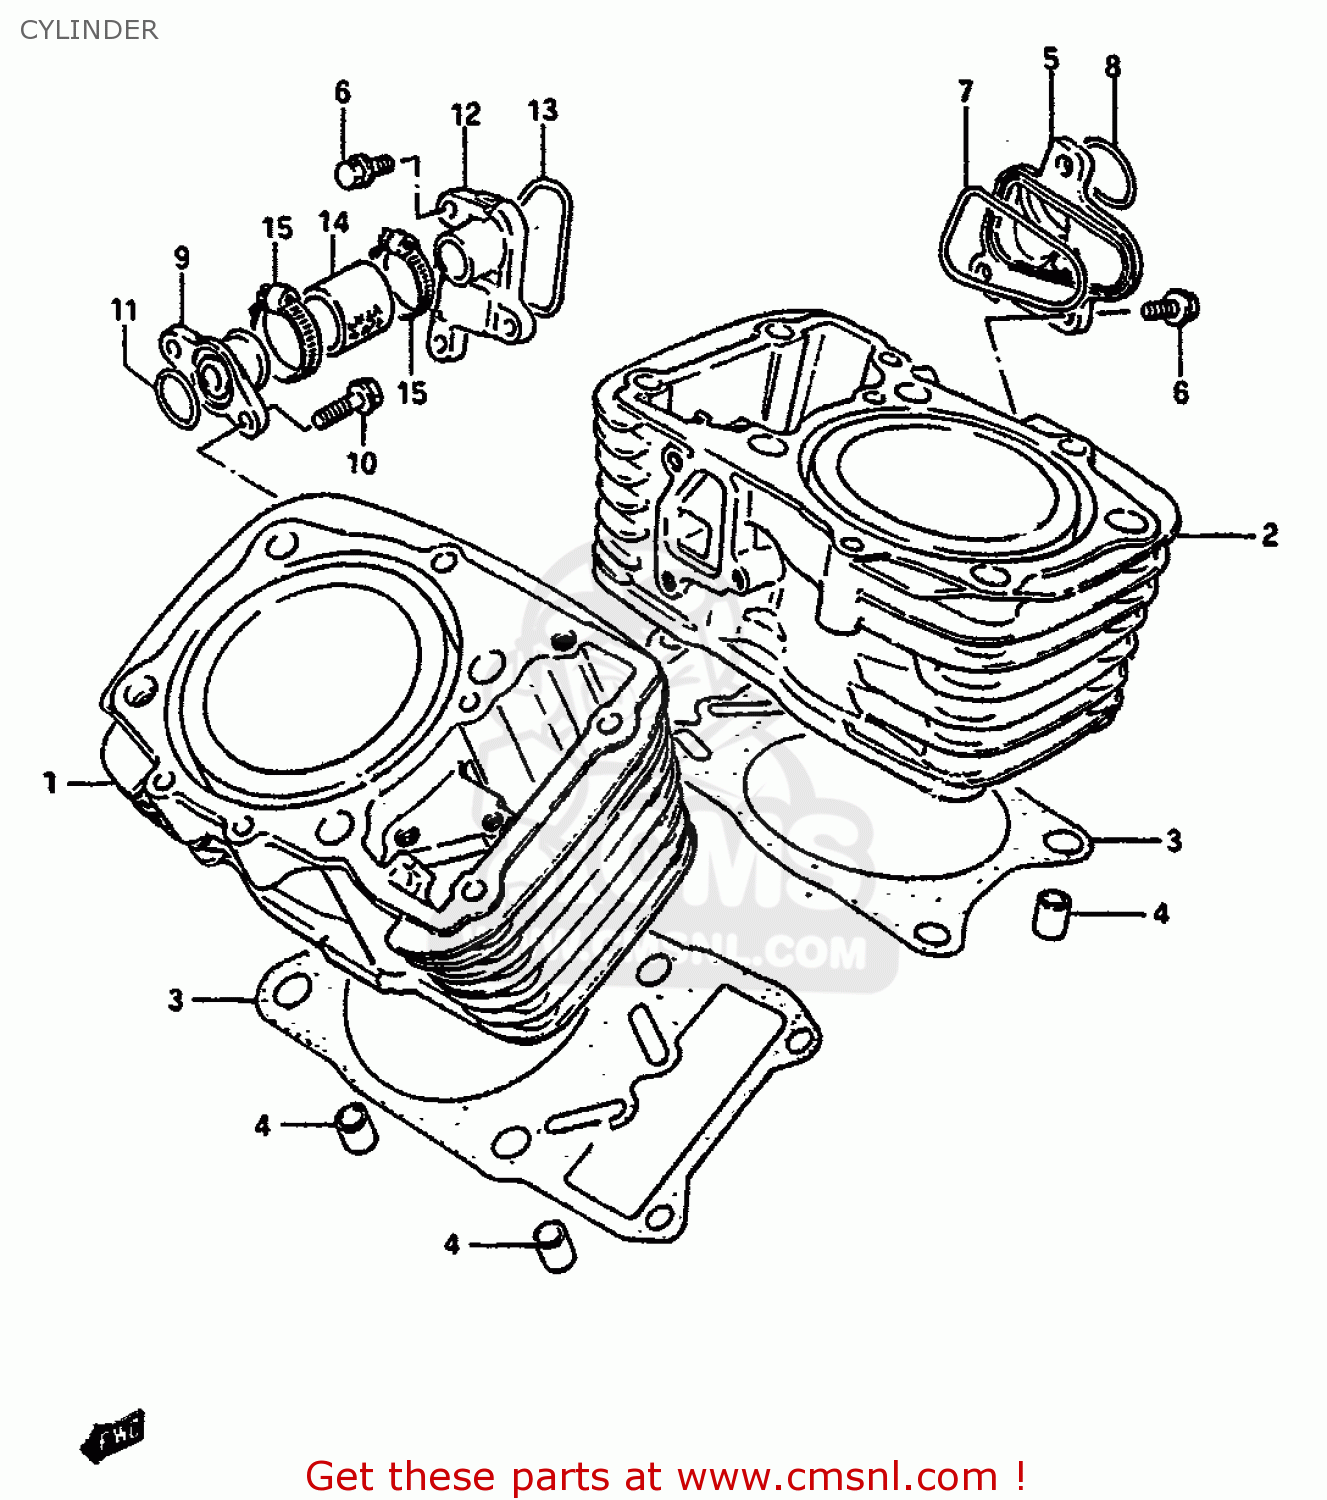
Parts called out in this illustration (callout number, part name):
1	CYLINDER,FR
2	CYLINDER,REAR
3	GASKET,CYLINDER (NA)
4	PIN
5	CHAMBER,WATER,INLET
6	BOLT
7	O RING,INLET WATER CHAMBER
8	O RING(D:2.3,ID:24.4)
9	UNION,WATER INLET
10	BOLT
11	O RING(D:2.4,ID:15.8)
12	CHAMBER,WATER,OUTLET
13	O RING,OUTLET WATER CHAMBER
14	HOSE,RADIATOR
15	CLAMP
